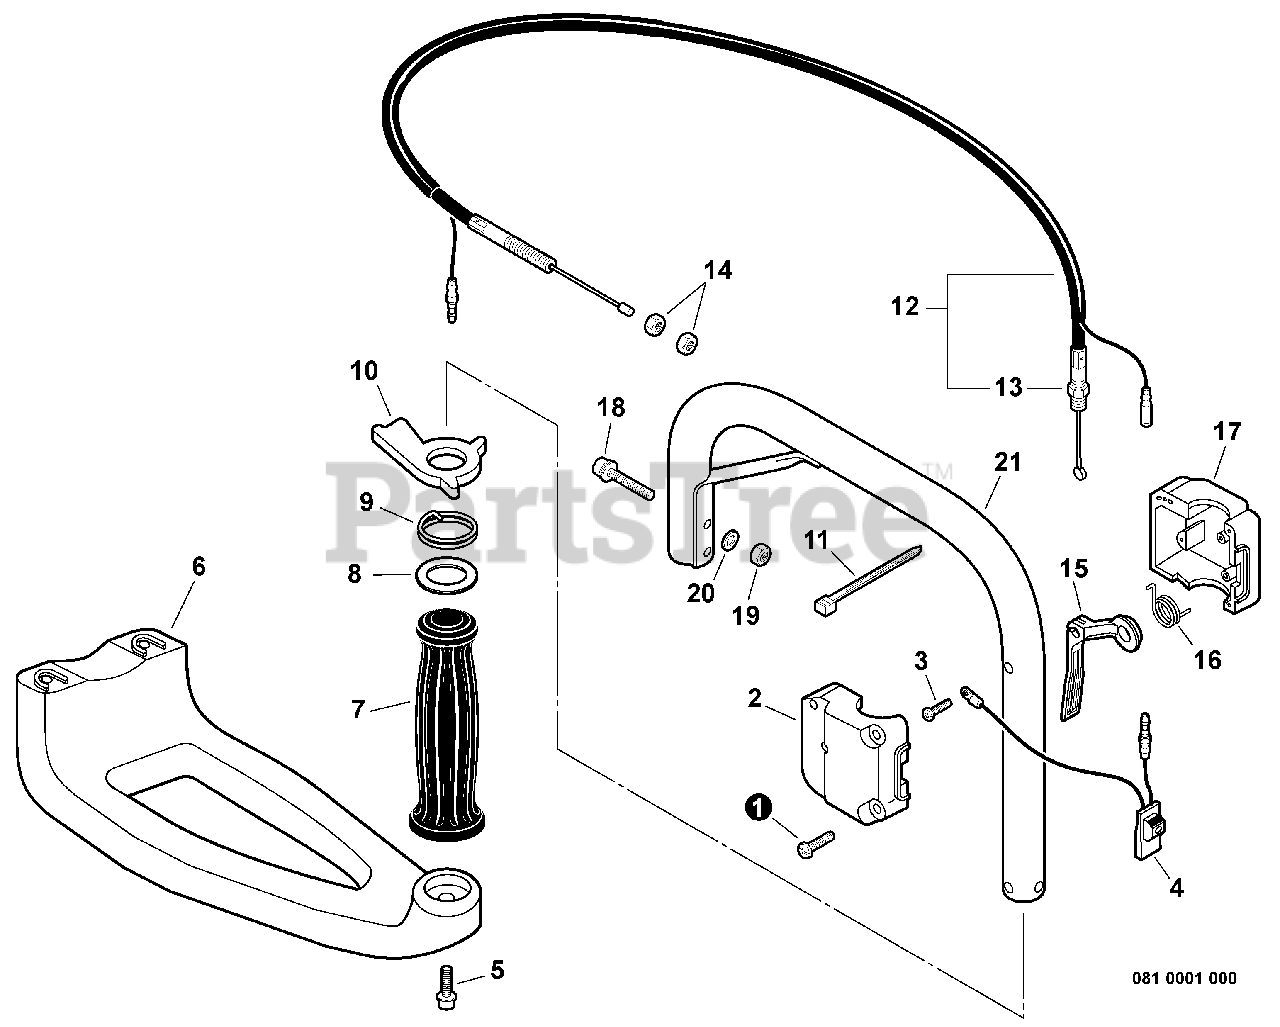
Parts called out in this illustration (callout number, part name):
1	SCREW 4×25
2	BRACKET, LEFT CONTROL
3	SCREW 4×30
4	SWITCH, ON-OFF
5	BOLT 5×16
7	GRIP, HANDLE
9	SPRING, THROTTLE LOCKOUT
10	LOCKOUT, THROTTLE
11	TIE, CABLE
12	CABLE ASSY, CONTROL
15	TRIGGER, THROTTLE
16	SPRING, THROTTLE RETURN
17	BRACKET, RIGHT CONTROL
18	BOLT M5×35
19	NUT, LOCK M5
20	WASHER 5.3×10×1
21	HANDLE, REAR
